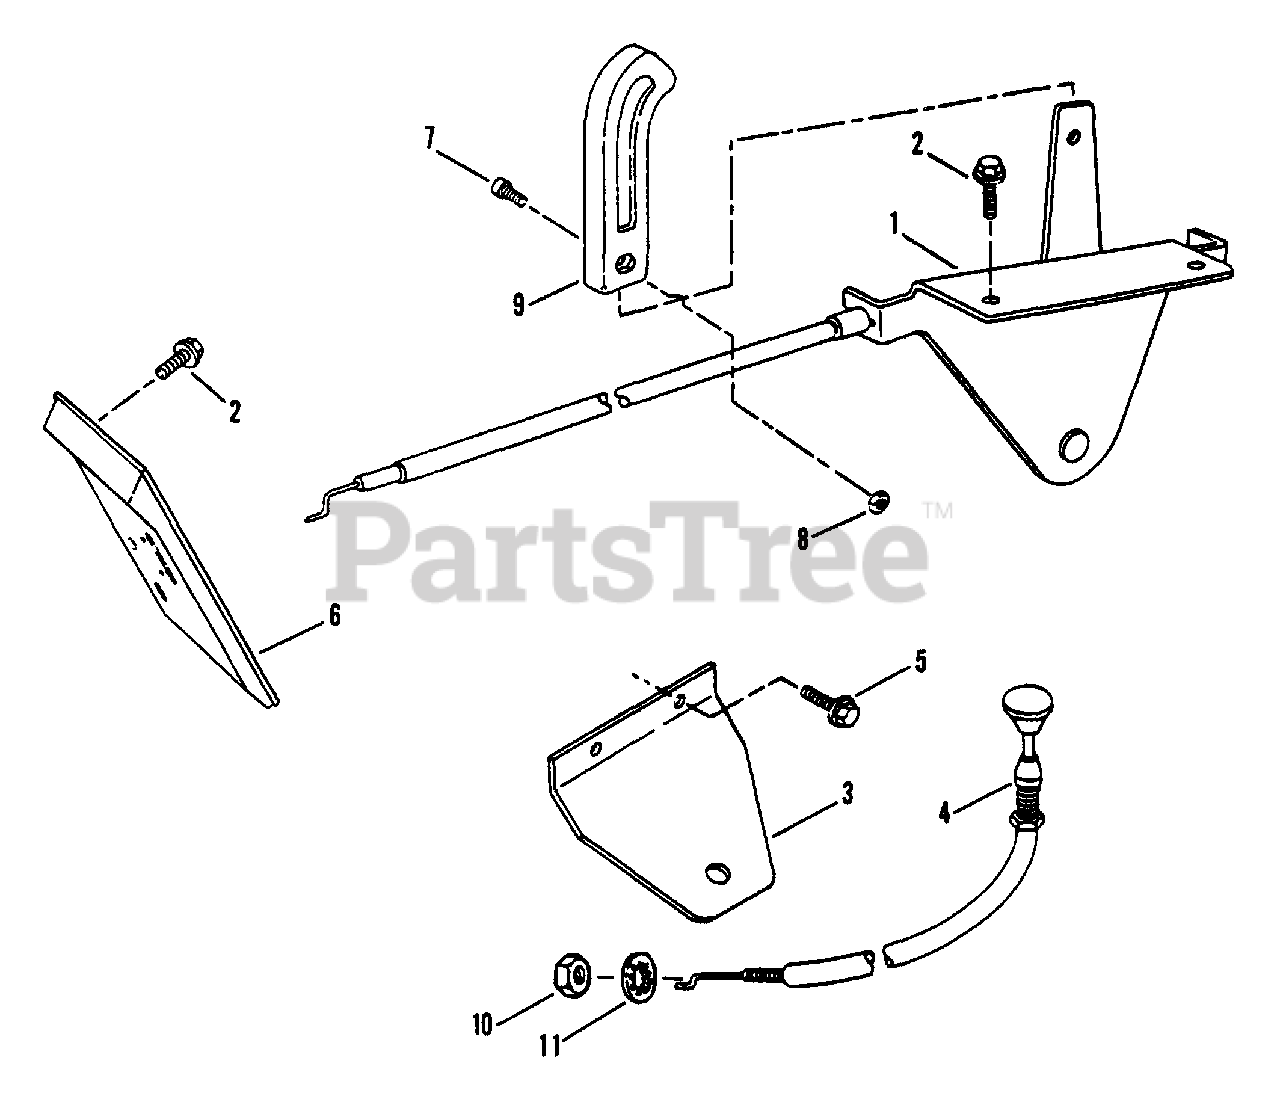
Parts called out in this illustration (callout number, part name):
1	CONTROL, Throttle (Briggs Engines)
2	SCREW, #10-24 x 1/2" Hex Washer Self-Tap (Torx)
3	PLATE, Throttle Control
4	CONTROL, Choke 36"
5	SCREW, 1/4-20 x 5/8" Self-Tapping
6	COVER, Dash Panel (Briggs 16)
7	SCREW, #8-32 x 3/8" Cross-Recess, Fillister Head
8	NUT, #8-32 Hex
9	KNOB, Throttle Control
10	NUT, 3/8-24 Hex
11	WASHER, 3/8 Internal Tooth Lock
